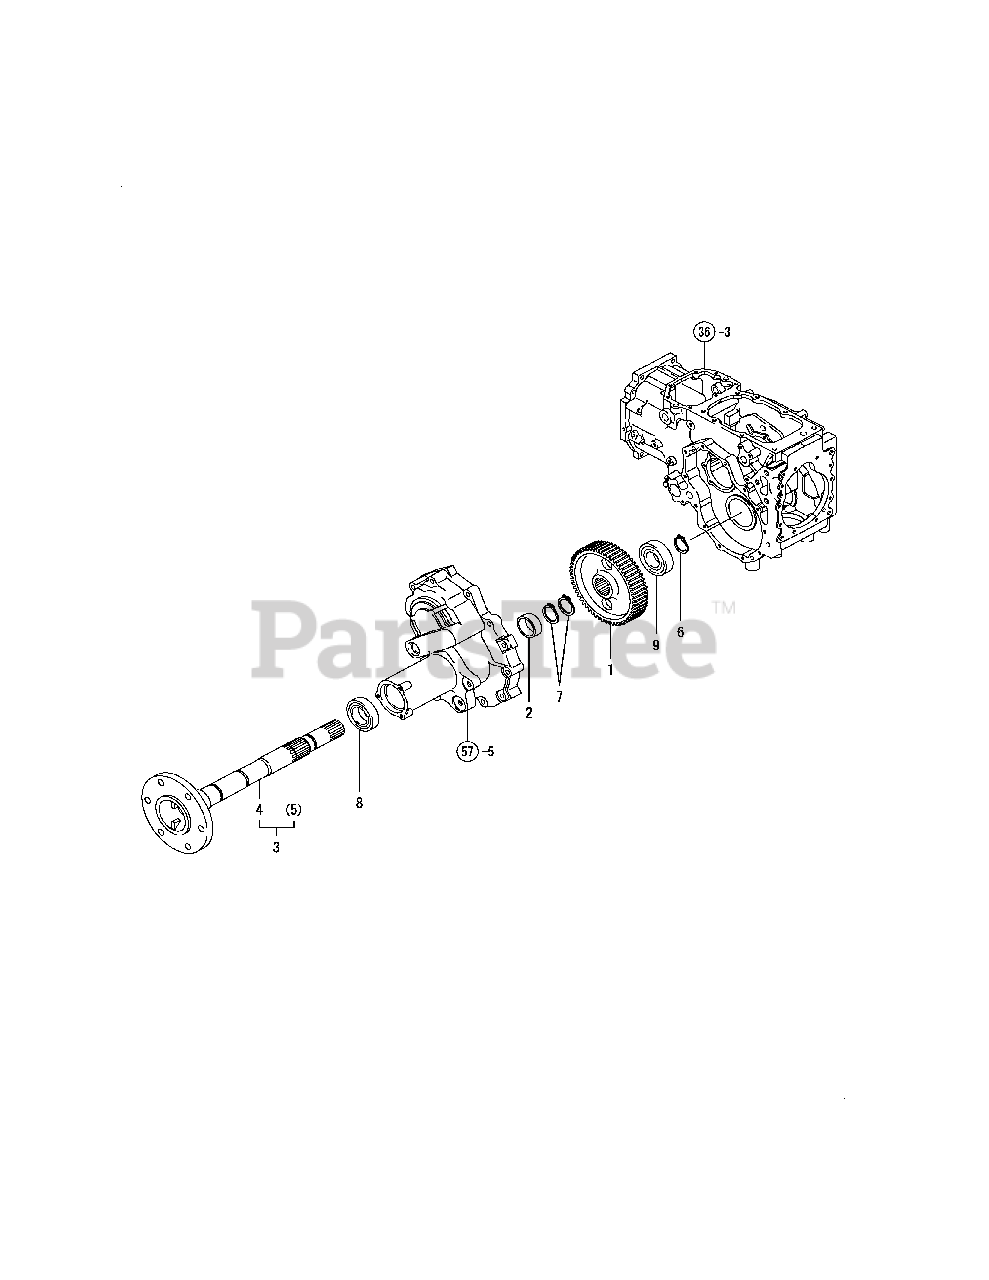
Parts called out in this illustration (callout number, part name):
1	GEAR, FINAL DRIVE
2	COLLAR 45X55X20
3	SHAFT, REAR AXLE
4	SHAFT, REAR AXLE
5	SHAFT, REAR AXLE
